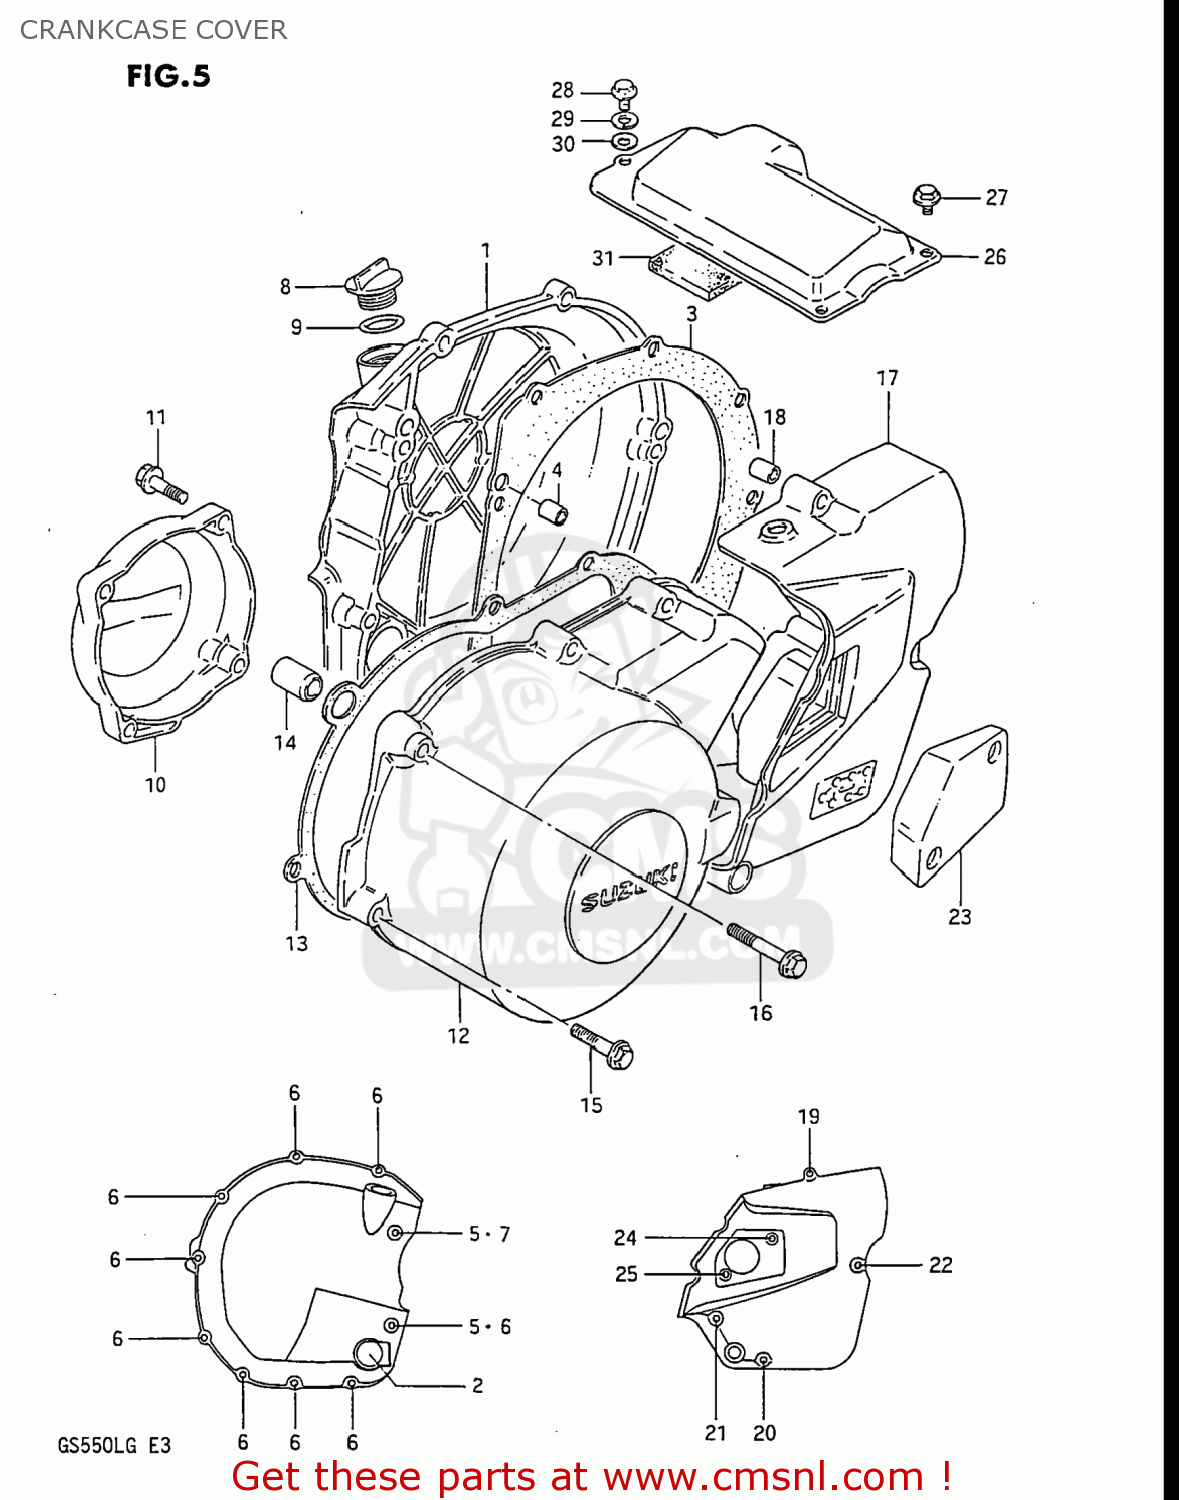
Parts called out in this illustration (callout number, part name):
1	COVER,CLUTCH
2	LENS,OIL LEVEL CHECK
3	GASKET,CLUTCH COVER (MCA)
4	PIN
5	WASHER
6	BOLT
7	BOLT
8	PLUG(20X10)
9	O RING(D:3.1,ID:16.8)
10	COVER,CONTACT BREAKER
11	BOLT
12	COVER
13	GASKET,MAGNETO COVER (MCA)
14	PIN (11X20)(SUS)
15	BOLT
16	BOLT
17	COVER,ENGINE SPROCKET
18	PIN
19	BOLT
20	BOLT
21	BOLT
22	BOLT
23	CAP,CLUTCH RELEASE ADJUST
24	SCREW 5X12
25	SCREW
26	COVER,STARTER MOTOR
27	BOLT
28	BOLT
29	WASHER,LOCK
30	WASHER
31	DAMPER,STARTER MOTOR CLUTCH
